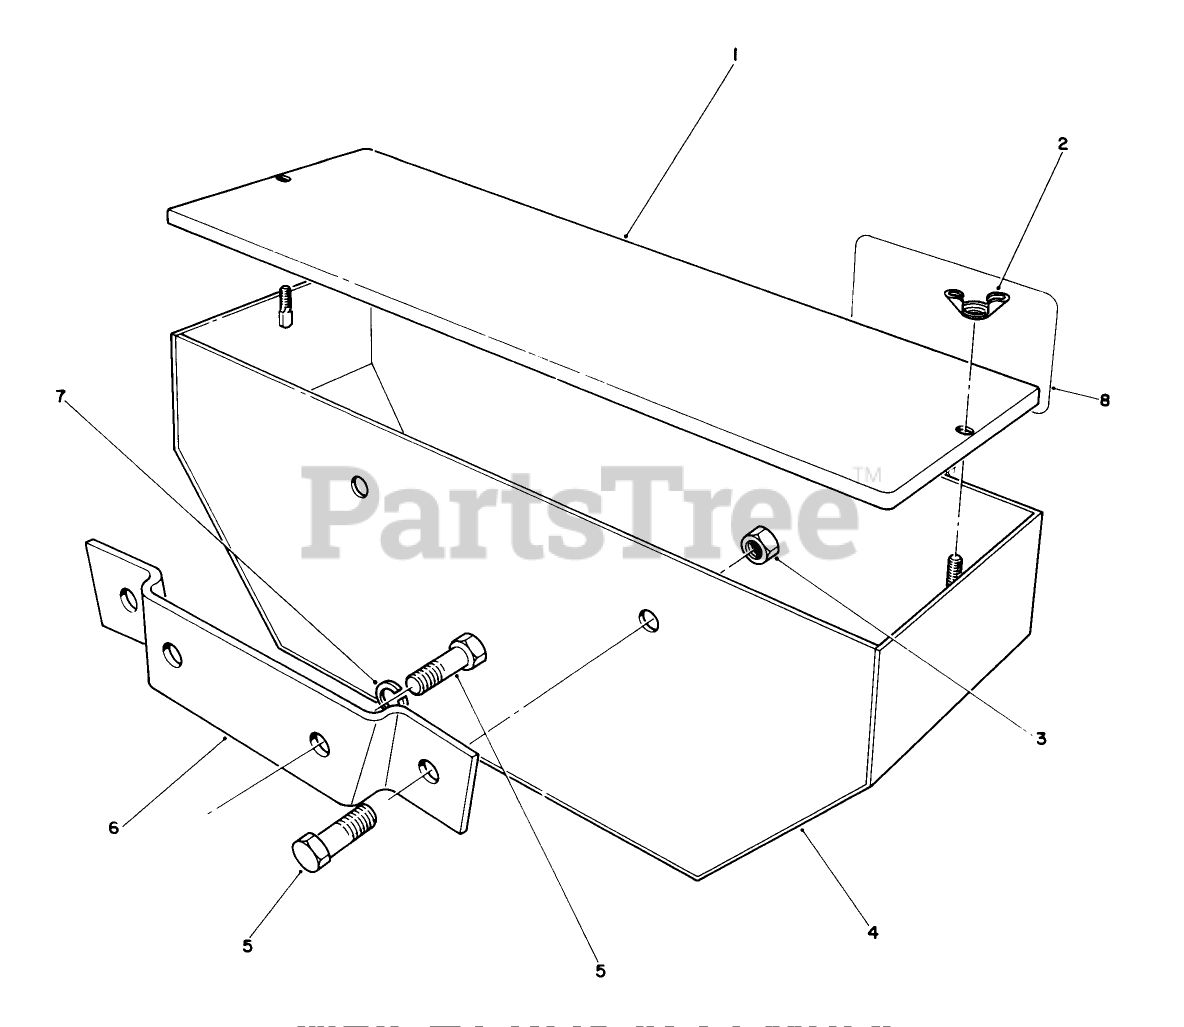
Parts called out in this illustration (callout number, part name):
1	WT BOX COVER R
2	NUT-WING
3	NUT-LOCK, NI
4	WEIGHT BOX WA
5	SCREW-HH
6	MOUNT BRKT R
7	WASHER-LOCK
8	Decal
